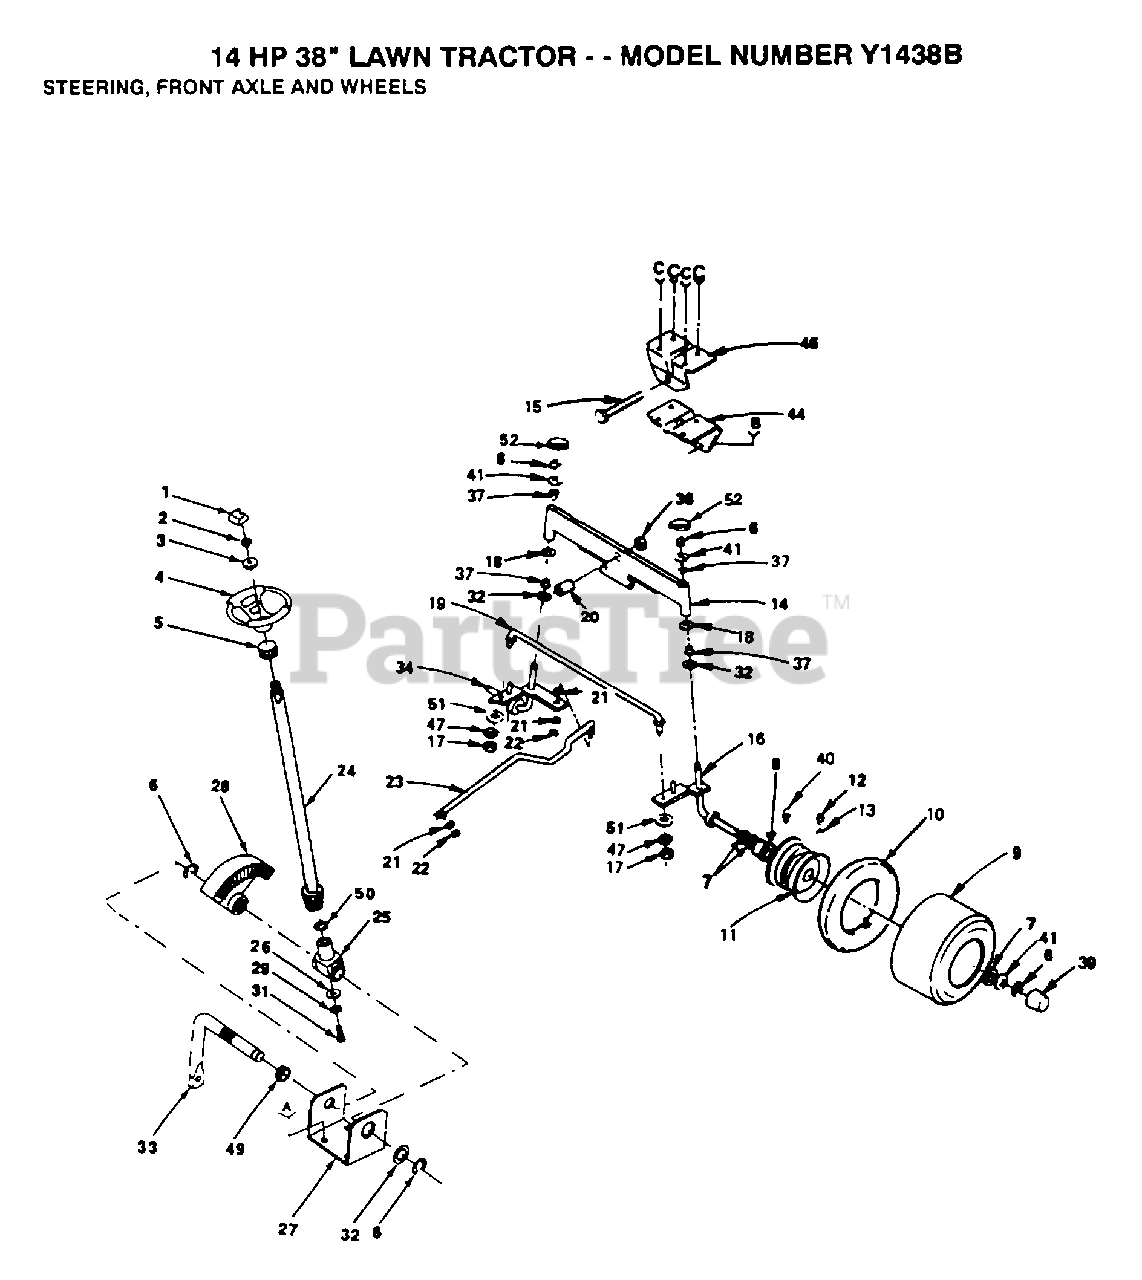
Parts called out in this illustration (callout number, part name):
1	INSERT STEERING
3	WASHER
5	ADAPTER LT
6	RING
7	WASHER
8	"FLANGE, BEARING"
10	TUBE.5.3/4.5/6
12	VALVE STEM LT
13	VALVE CAP
14	FRONT AXLE
15	BOLT LT
17	NUT.LOCK.5/16-24
18	WASHER
19	ROD TIE
20	BEARING
21	LOCKWASHER
24	STEERING SHAFT
25	SUPPORT.SHAFT
27	"BRKT,STEERING"
29	LOCKWASHER
31	"SCREW,SPECIAL"
32	WASHER .T
34	SPINDLE-LH LT
37	COL. SRTG. BEAR.
39	HUB CAP
40	FITTING LT
41	WASHER
44	SUPPORT.SADDLE.FT
46	SCREW LT
47	LOCKWASHER
49	NYLINER T
50	THRUST WASHER
51	WASHER M
52	CAP
